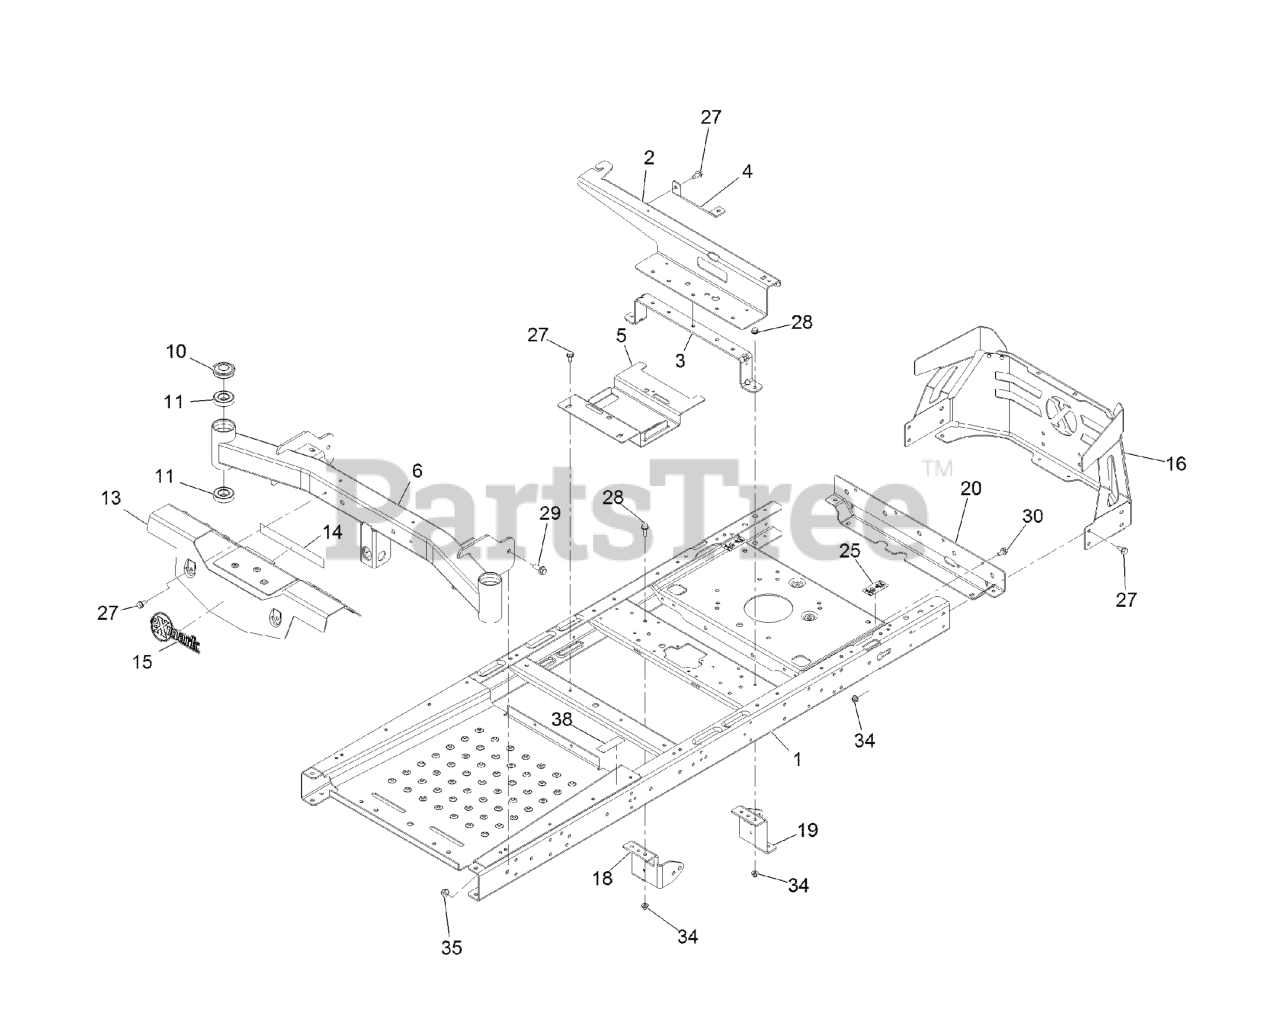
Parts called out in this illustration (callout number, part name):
1	RIVETED FRAME ASM (WIDE LEVER)
2	BRACE-SEAT, REAR (WIDE)
3	SUPPORT-POD
4	SUPPORT-TANK, REAR
5	BRACKET-BATTERY
6	AXLE-FRONT 50
10	CAP-GREASE
11	BEARING-BALL
13	FOOTREST ASM
14	DECAL-WARNING
15	DECAL, EXMARK LOGO
16	GUARD-ENGINE, ASM WIDE
18	MOUNT-HYDRO, FRONT (RIGHT
19	MOUNT-HYDRO, FRONT (LEFT)
20	CROSSMEMBER-REAR, WIDE
25	DECAL-BYPASS
27	Screw-HWH 5/16-18 X 3/4 Tf
28	SCREW-HHF
29	SCREW-HHF 3/8-16 X 1
30	SCREW-HHF
34	NUT-HF, NI
35	NUT-HF, NI
38	DECAL-BRAKE, PARKING
